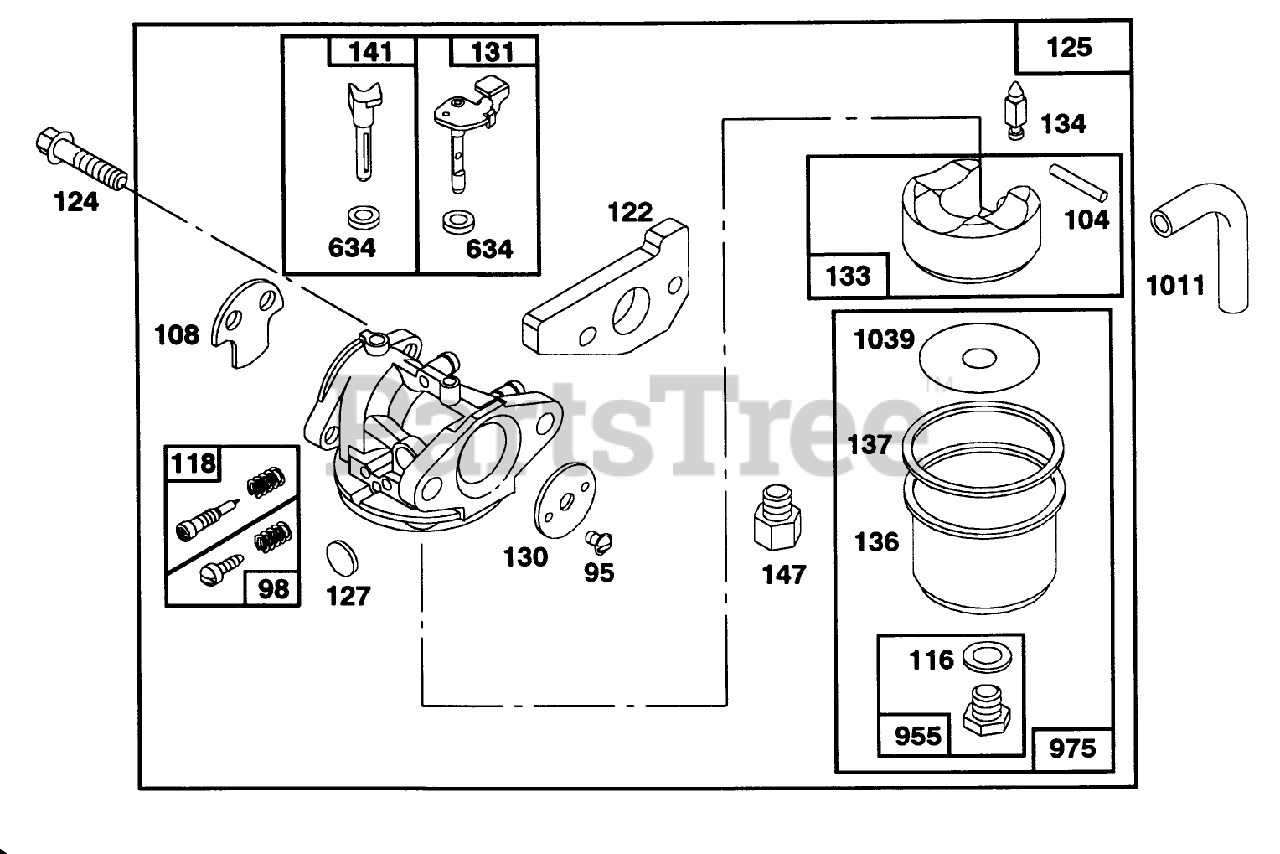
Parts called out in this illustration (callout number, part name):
95	Valve-Choke
98	Idle Speed Kit
104	Spring
108	Valve-Choke
116	Washer-Sealing
118	Valve-Needle
122	Adapter Assy
124	Screw-Hex Head (carb mtg)
125	Carburetor Assy
127	Plug-Welch
130	Valve-Throttle
131	Shaft and Lever
133	Float-Carburetor
134	Valve-Inlet (Includes Seat)
136	Bowl-Fuel
137	Float Bowl Gasket
141	Shaft-Choke
147	Adapter-Jet Note: For High Altitude Jet, Order Part No. 494236.
634	Washer-Seal
955	Screw-Hex Head
975	Bowl Assy-Carburetor
1011	Tube-Vent
1039	Limiter-Float
